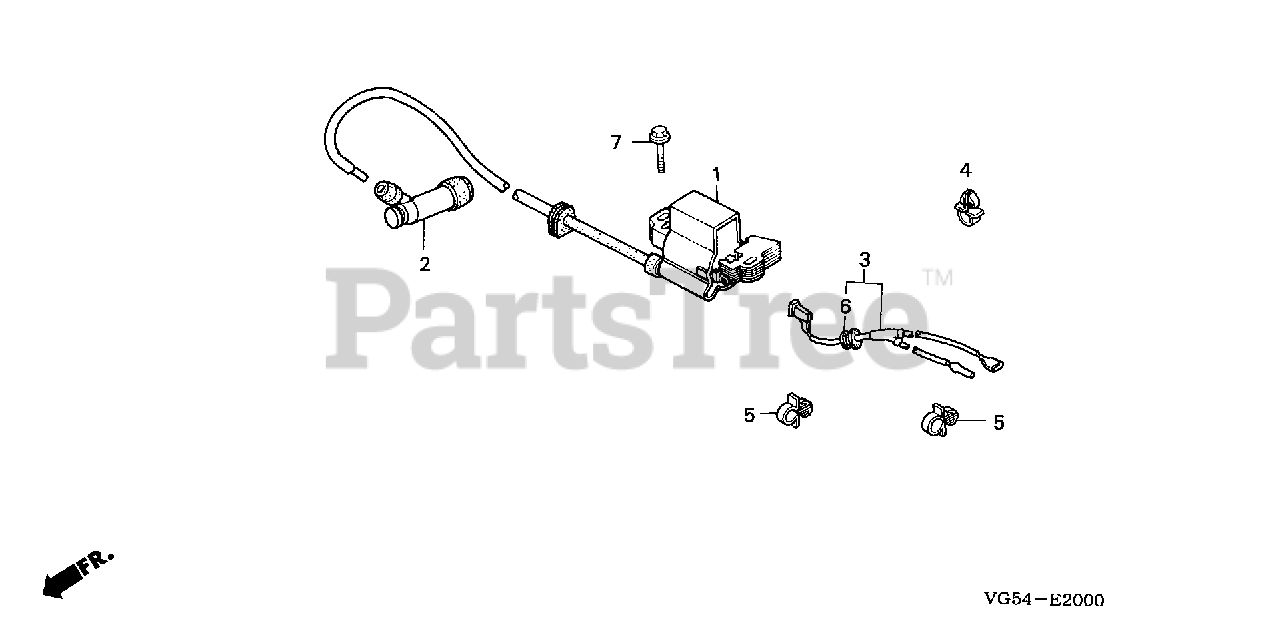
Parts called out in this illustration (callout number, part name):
1	COIL ASSY., IGNITION
2	CAP ASSY., NOISE SUPPRESSOR
3	WIRE, STOP SWITCH
4	HOLDER, STOP SWITCH WIRE
5	CLIP A, BRAKE PIPE
6	GROMMET, WIRE
7	BOLT, FLANGE (6X28)
